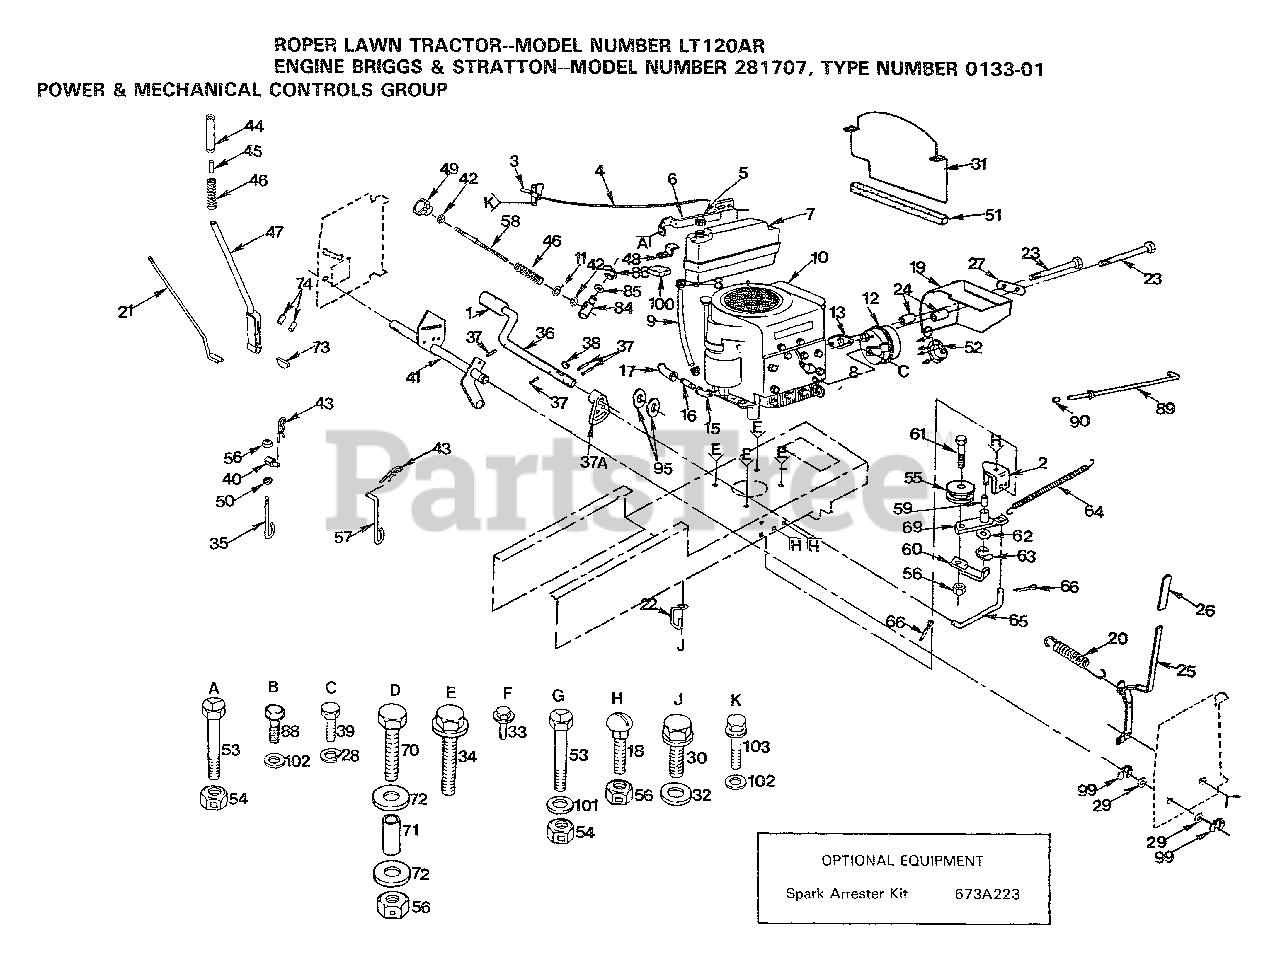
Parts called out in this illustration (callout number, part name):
1	PEDAL COVER T
6	SUPPORT-TANK LT
9	HOSE T
10	ENGINE 12 H.P. TYPE 0201-01
11	WASHER
12	MUFFLER LTV
15	STREET ELBOW LT
16	PIPE NIPPLE
17	ELBOW
18	BOLT
19	BAFFLE ASSY LT
20	"SPRING.EXT.8.5"""
21	ROD ASSY-LEVER LT
23	BOLT YT
24	SPACER LT
27	CLIP-MUFFLER LT
28	LOCKWASHER
29	WASHER
30	SCREW
31	"VERTICAL LT, BAFL"
32	WASHER
34	SCREW
35	LINK LIFT LT
36	FOOT SHAFT PEDAL
37A	ARM BRAKE LT
39	BOLT
42	NUT
46	SPRING T
47	LEVER ASSY LT
48	BRACE-TANK LT
52	DEFLECTOR.222573
53	BOLT
58	ROD ADJUST LT
59	"LY, BEARING"
62	WASHER T
63	KLIP RING
64	"SPRING, RETURN LT"
65	"LINK, CLUTCH T"
66	COTTER PIN
85	WASHER
86	KLIP RING
88	SCREW LT
90	PLUNGER CAP T
99	RING
100	PAD-SPACER T
101	WASHER
102	WASHER
